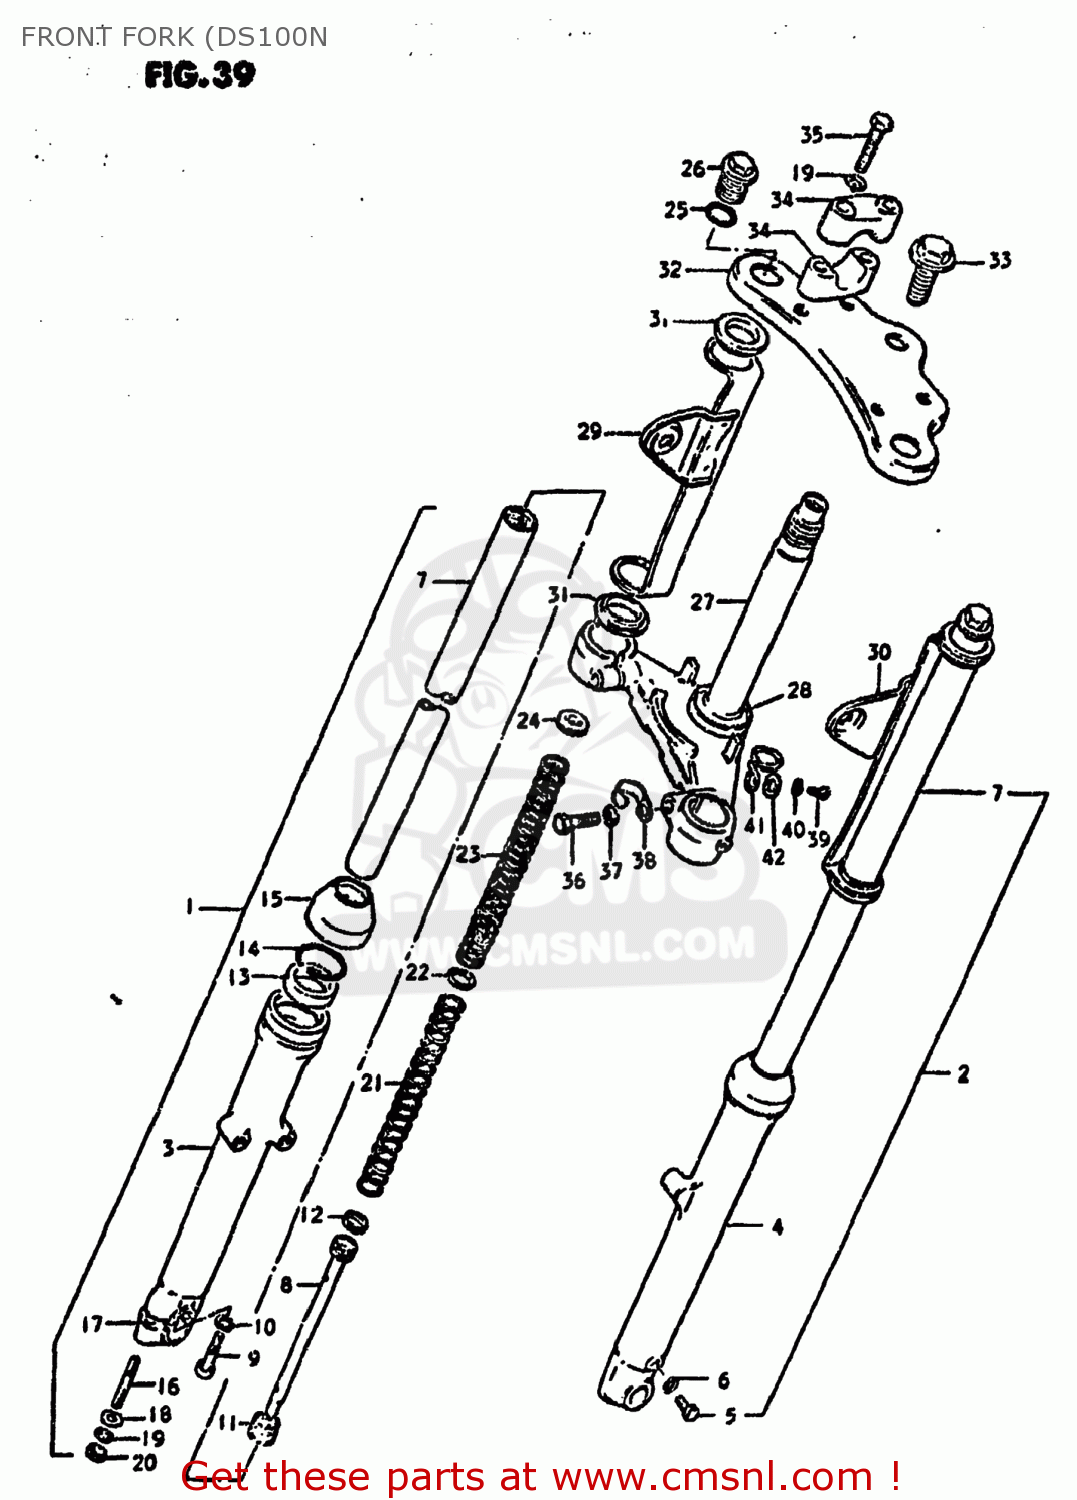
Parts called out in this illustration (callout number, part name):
0	DAMPER SET
1	DAMPER ASSEMBLY,RIGHT
2	DAMPER ASSEMBLY,LEFT
3	TUBE,FORK,OUTER,RIGHT
4	TUBE,FORK,LEFT,OUTER
5	BOLT(6X8)
6	GASKET,DRAIN,PLUG (NAS)
7	TUBE,FORK,INNER
8	PIPE,FORK SEAT
9	BOLT(8X27)
10	GASKET (NAS)
11	SPRING,REBOUND
12	RING,PISTON
13	OIL SEAL,FRONT FORK
14	RING,OIL SEAL STOPPER
15	BOOT
16	STUD 8X25
17	HOLDER,AXLE(BLACK)
18	WASHER
19	LOCK WASHER
20	NUT
21	SPRING,FRONT FORK
22	JOINT,SPRING
23	SPRING,FRONT FORK
24	NUT,FORK SPRING,UPPER
25	O-RING,FORK INNER TUBE
26	CAP
27	STEM,STEERING
28	RACE,STEERING OUTER LWR
29	BRACKET,HEADLAMP,RIGHT
30	BRACKET,HEADLAMP,LEFT
31	CUSHION
32	HEAD,STEERING STEM
33	BOLT
34	HOLDER,HANDLEBAR
35	BOLT 8X55
36	BOLT
37	WASHER,LOCK 12
38	CLIP
39	SCREW 6X12
40	LOCK WASHER
41	CLIP
42	WASHER
